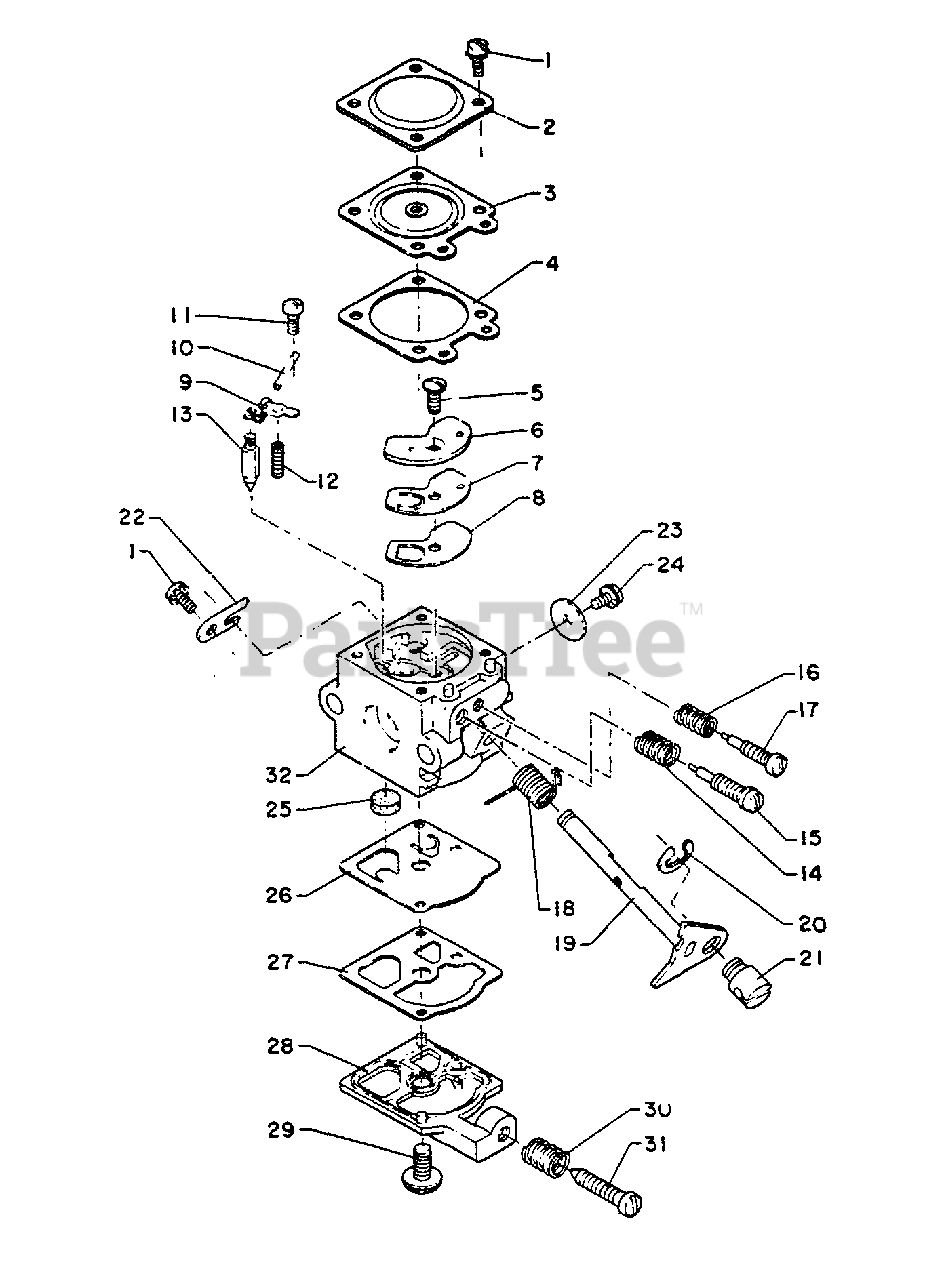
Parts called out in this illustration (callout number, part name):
2	COVER, METERING DIAPHRAGM
3	DIAPHRAGM, METERING
4	GASKET, METERING DIAPHRAGM
5	SCREW, CIRCUIT PLATE
6	PLATE, CIRCUIT
7	VALVE, CHECK
8	GASKET, CIRCUIT PLATE
9	LEVER, METERING
10	PIN, METERING LEVER
11	SCREW, METERING LEVER PIN
13	VALVE, INLET NEEDLE
14	SPRING, NEEDLE
15	NEEDLE, HIGH SPEED
16	SPRING, NEEDLE
17	NEEDLE, IDLE
18	SPRING, THROTTLE RETURN
19	SHAFT, THROTTLE
20	RING, RETAINING
22	CLIP, THROTTLE SHAFT
23	VALVE, THROTTLE
25	STRAINER
26	DIAPHRAGM, FUEL PUMP
27	GASKET, FUEL PUMP
28	COVER, PUMP
30	SPRING, IDLE ADJUST
31	SCREW, IDLE ADJUST
32	BODY, CARBURETOR
